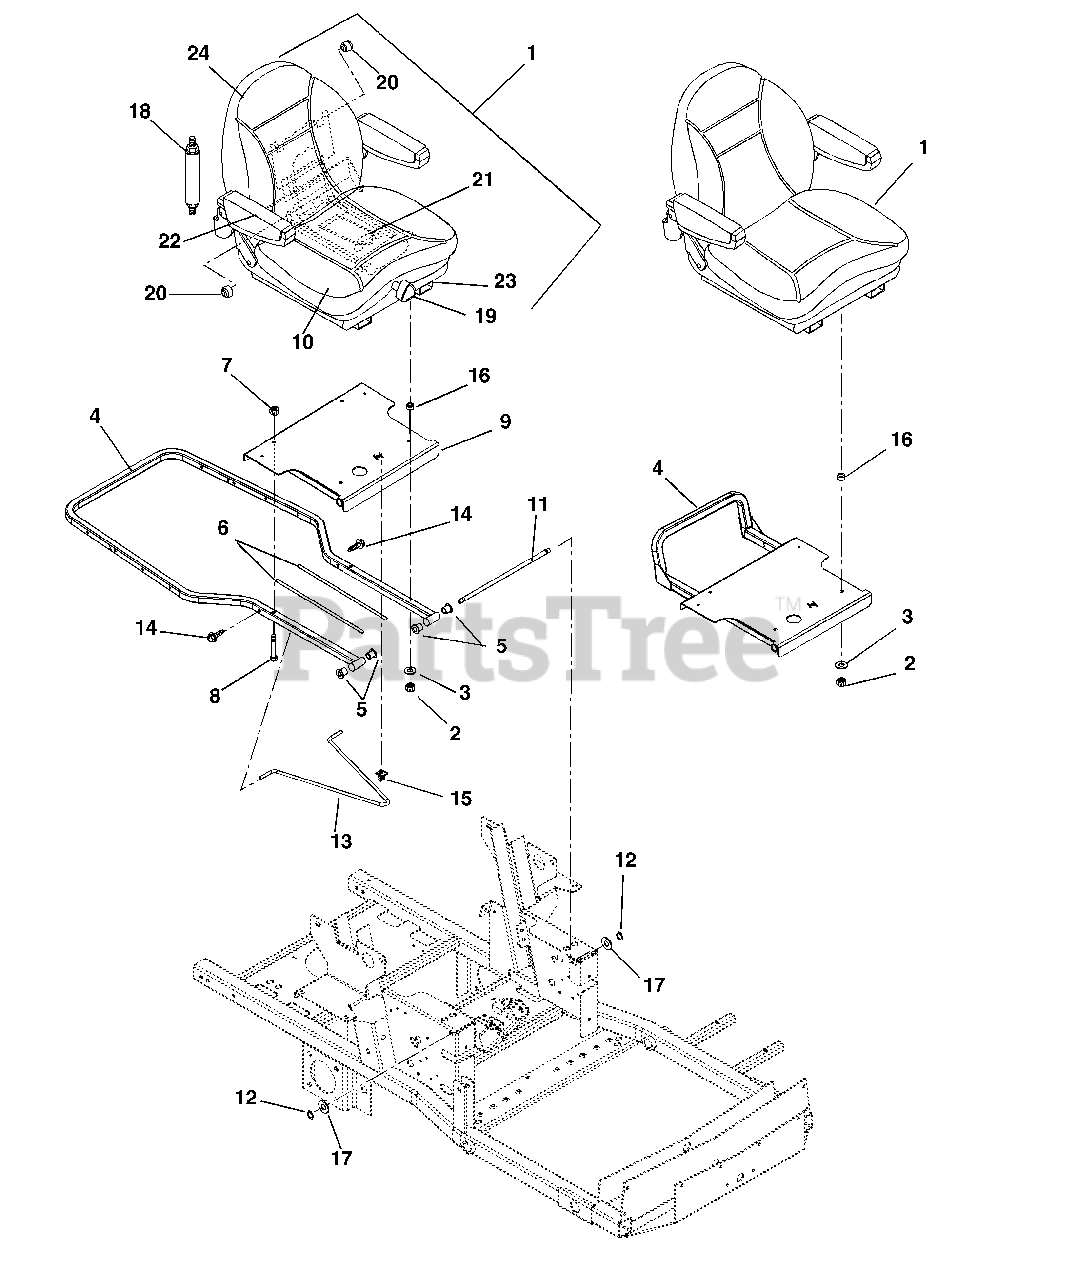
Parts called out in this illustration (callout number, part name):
1	Seat-Suspension
1	Seat- Suspension
2	Nut-Locking-Nylon M8-1.25
2	Nut-Locking-Nylon .312-18
3	Washer-Flat-Steel .38 x .875 x .083
4	Weldment- Hood Frame
4	Weldment - Seat Frame
5	Bushing-Flange .515 x .750 x .745 x 1.00
6	Tape -VHB 4941F
7	Nut-Locking-Top-Flange .38-16
8	Bolt-Rib Neck .38-16 x 1.50
9	Weldment-Seat Pivot Plate
10	Kit-Cushion (1 per carton)
11	Rod-Seat Frame Pivot
12	Ring-Retaining-External .500 x .050
13	Rod-Prop
14	Screw-Tapping .25-20 x .50 Hex Washer Head
15	Clip
16	Bushing-Sleeve .377 x .624 x .235
17	Washer-Flat-Steel .531 x 1.06 x .095
18	Kit-Damper w/Hardware
19	Kit-Knob (1 per bag)
20	Kit-Roller (4 per bag)
21	Kit-Spring Cable (1 per bag)
22	Kit-Arm Pad (1 per bag)
23	Kit-Adjuster (1 per carton)
24	Kit-Seatback
